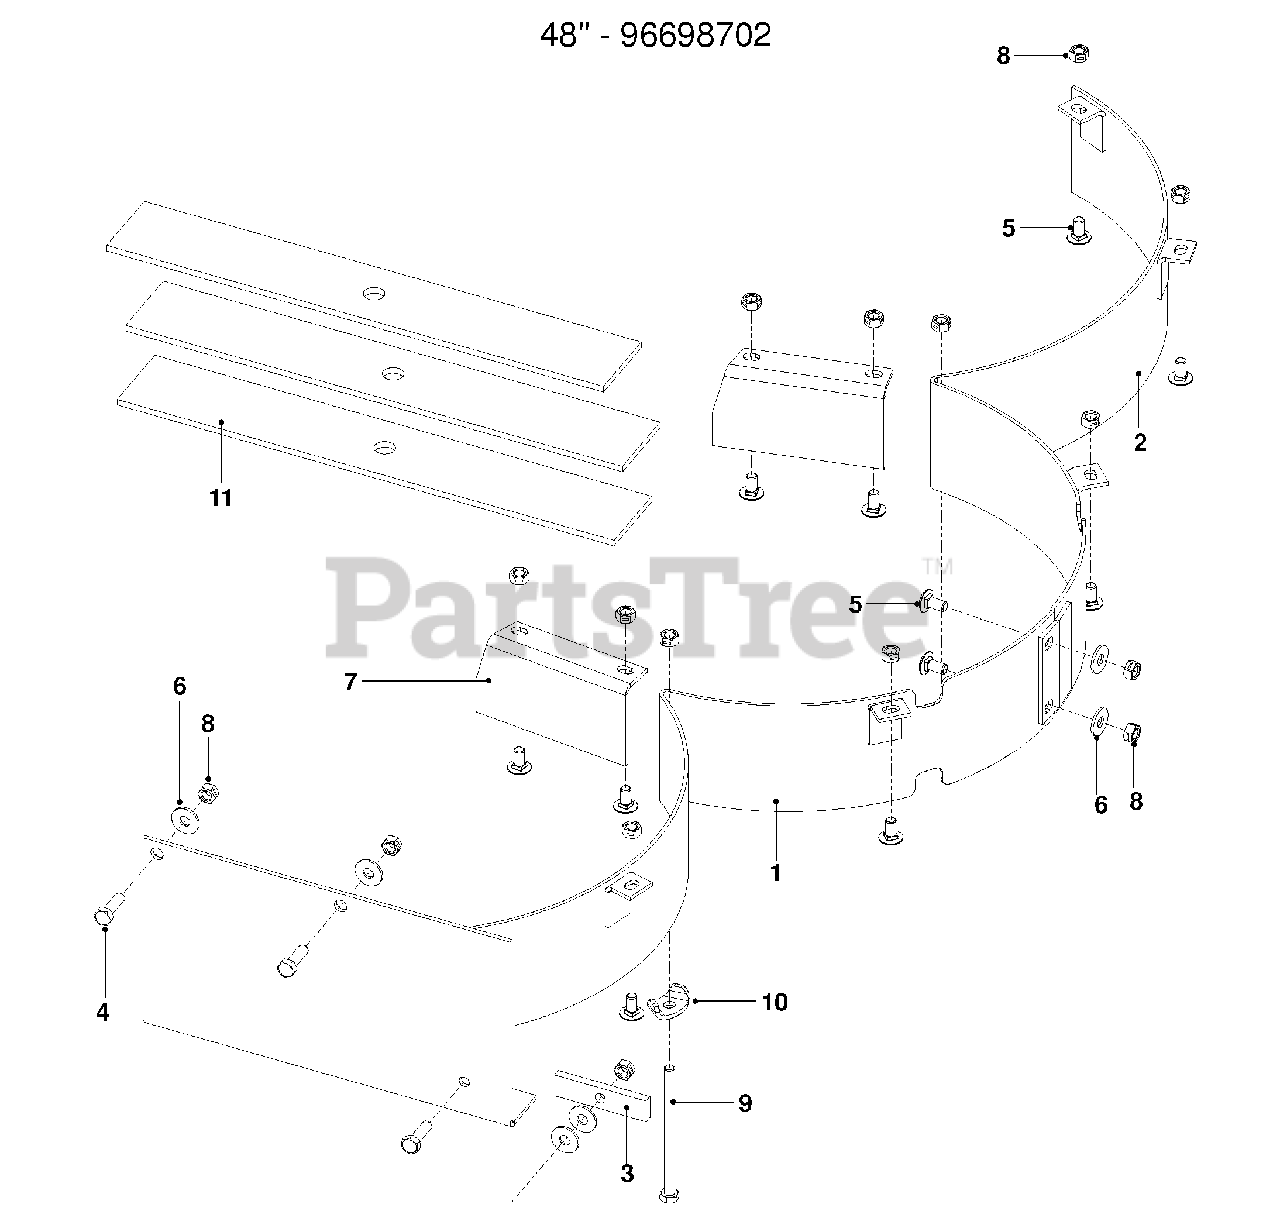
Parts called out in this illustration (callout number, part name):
1	Baffle Wldt, Black 48"
2	Baffle Wldt, Black
4	Hcs 5/16-18 X 1 Gr 5
5	Rhsnb 5/16-18 X 5/8 Gr 5
6	Washer 5/16 Std Flt
7	Center Deflector, Black
8	Nut 5/16-18 Hex Ctrlk
9	Hcs 5/16-18 X 4 1/2 Gr 5
10	Cap, Black
11	Mulch Blade 16 1/4"
